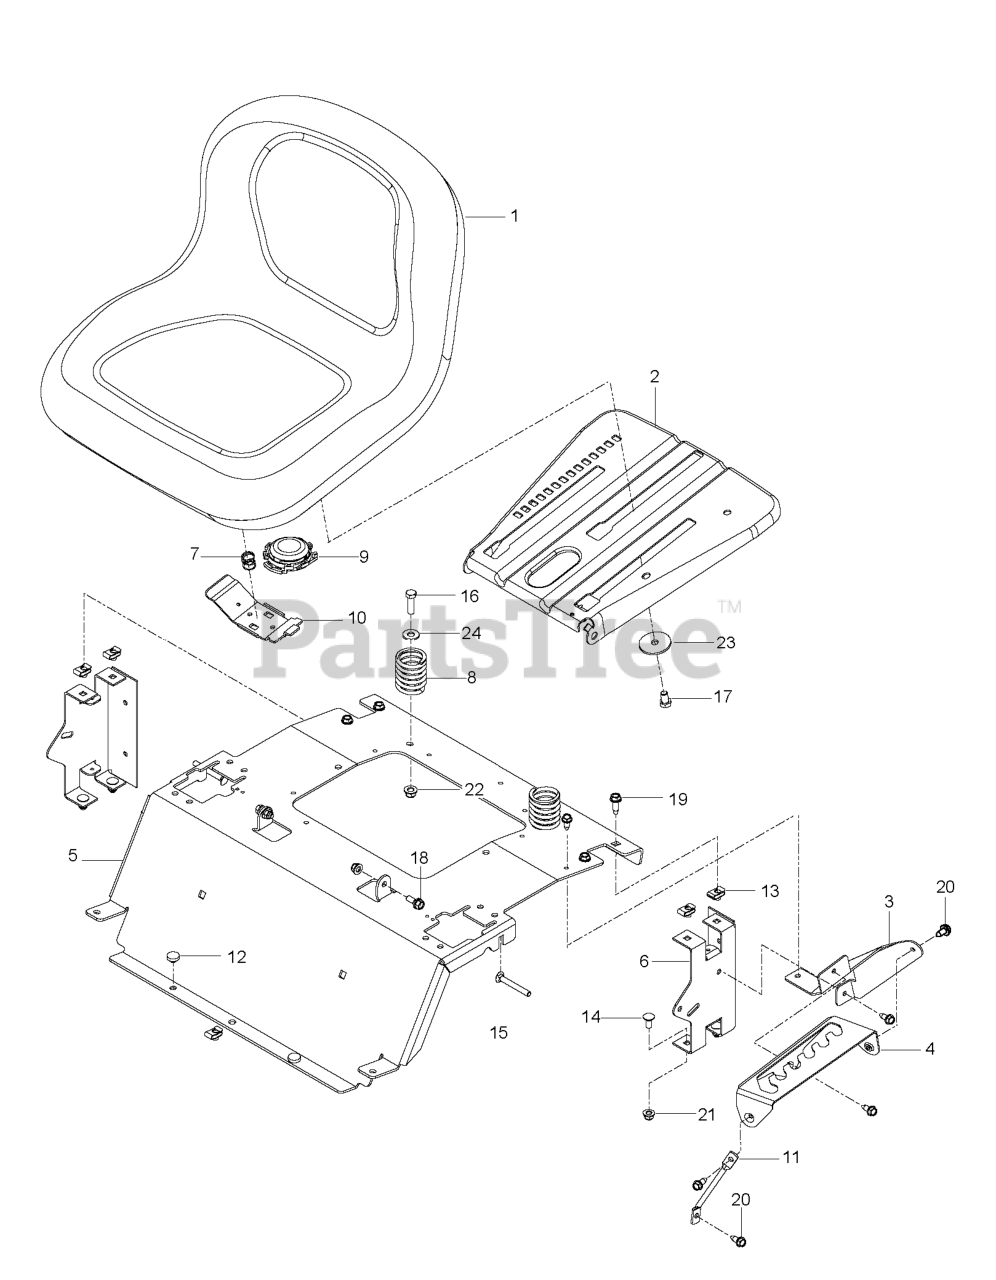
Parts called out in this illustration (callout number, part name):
2	DRAWBAR.STGT
3	APPLIQUE.SUBASM.GT.HUSQ.II
5	RP DASH.UPP.GT2.DUAL.RD.PTO.MC
14	HOOD.ASM.HUSQVARNA.GT.TEX.422
15	LENS.HEADLIGHT.LH.GTII.2011
18	GRILLE.SUBSTRATE.2011.
25	LENS.HEADLIGHT.RH.GTII.2011
36	SCREW 5/16"
37	FENDER.PNT.TX.GT.CH/FW/DL.HUSQ
58	BRKT.SUPPORT.FNDR/TANK
68	Screw 5/16-18 x 1/2 Hex, Self Tapping 5/16-18 x 1/2
125	CLIP.FUEL.LINE
130	SCREW.#10 X 0.750.BOS
137	BUMPER DASH
146	BOLT.RDHD.SHT.SQNK.3/8-16X5/8
150	AIR.DUCT.GTV.BLACK
151	BRACKET.PIVOT.HOOD.GT.HUSQ.II
152	SHIELD.BROWNING.PNT.GT.V2
159	SCREW, 3/8-16X3/4
161	CONSOLE.WINDOW.FUEL.HUSQ.GT
162	SCREW.HI-LO.CONSOLE
165	SUPPORT.TANK.REAR.B/TE
175	PLATE.CROSSMEMBER.HUSQ
176	SCREW.#10-24X5/8.RN.QU
177	BUSHING STEERING
180	CHASSIS.TEX.BOLTED
182	DASH.LOWER.COMMON.12V.ADAPTOR
183	BOLT.5/16-18X1-1/4 FULL THD
189	SCREW
191	INSERT.REFLECTIVE.RH.HUSQ.GTII
194	NUT LOCK HEX FLANGE 5/16-18
196	CONSOLE.ASM.DECKLIFT.HUSQGT.DL
199	PLATE.DECK.LIFT.HUSQVARNA.GT
202	VENT.SIDE.RH.GT.HUSQ.II.
203	VENT.SIDE.LH.GT.HUSQ.II.498
204	VENT.TOP.HUSQ.GT2
205	SIDE.TRIM.RH.GT.HUSQ.II
206	SIDE.TRIM.LH.GT.HUSQ.II.GRAY
207	BEZEL LIGHT.RH.GT.II.MYLAR
208	BEZEL LIGHT.LH.GT.II.MYLAR
214	CLIP.RETAINER.TINNER.
217	ROD.PIVOT.HOOD
221	REFLECTOR.LH.TEX GT HU
228	STUD.FASTNER.W/ANTI-ROTATE
235	SPACER FENDER
236	NUT.CENTERLOCK.5/16-
297	INSERT.REFLECTIVE.LH.HUSQ.GTII
306	NUT LOCK FLG 3/8-16 UNC
335	COVER.LOWER.DASH.RH.BLACK
336	COVER-LH.LOWER.DASH.GT2.BLACK
350	KIT GUARD BRUSH
375	BUMPER CLIP-ON. DASH 1"
